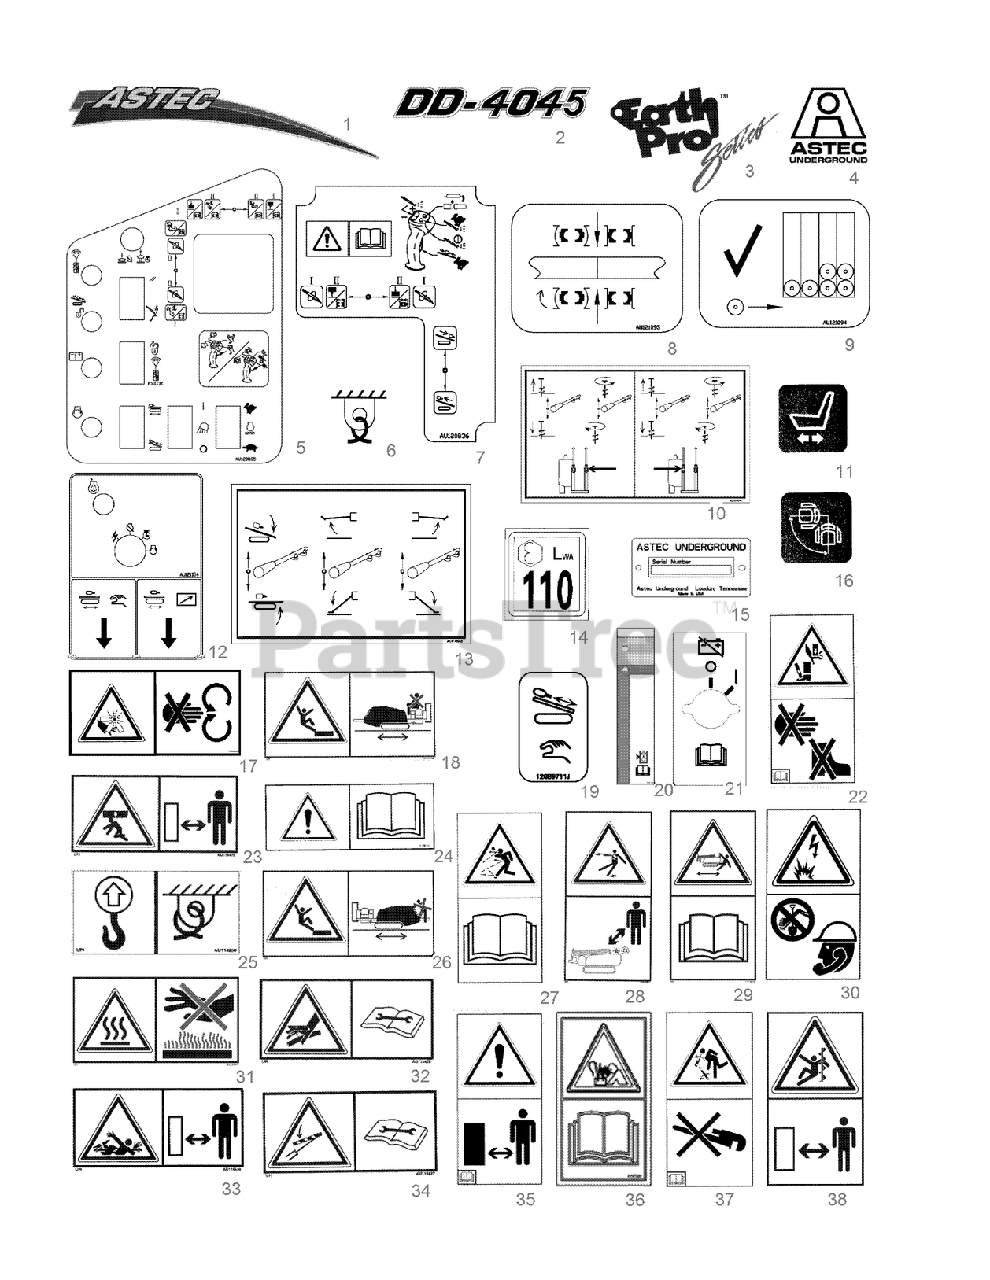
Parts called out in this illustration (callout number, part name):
1	DECAL - Astec, Red and Blue Pattern
2	DECAL - Model DD4045
3	DECAL - Earth Pro, Medium Size
4	DECAL - A, Astec Underground
5	DECAL - Left Joystick Overlay
6	DECAL-Tie Down
7	DECAL - Right Joystick Overlay
8	DECAL - Pipe Breakout Clear
9	DECAL - Pipe Return Clear
10	DECAL - Stakedown Setup
11	DECAL - Seat Fore/Aft
12	DECAL - Rear Controls (Inside Box)
13	DECAL - Stabilizer/Thrust Frame Setup
14	DECAL - Danger, Bystander
15	PLATE - Serial Number
16	DECAL - Seat Pivot In/Out
17	DECAL-Fan Entanglement
18	DECAL - Warning, No Riders (Front), ISO
19	DECAL - Remote Plug
20	DECAL-Hydraulic Oil Level
21	DECAL-Master Disconnect Switch
22	DECAL - Danger, Crush, Hands and Feet, ISO
23	DECAL - Danger, Crush From Above, ISO
24	DECAL - Warning, Read Operators Manual, ISO
25	DECAL-Tie Down / Lift Hook
26	DECAL - Warning, No Riders While Tramming, ISO
27	DECAL - Warning, Flying Objects, ISO
28	DECAL - Danger, Strike Alert Electrocution Hazard, ISO
29	DECAL - Danger, Runover Hazard, ISO
30	DECAL - Call Before You Dig, ISO
31	DECAL-Hot Surface
32	DECAL - Danger, Hydraulic Components Under Pressure, ISO
33	DECAL - Danger, Entanglement Hazard, Small, ISO
34	DECAL - Warning, Use Cylinder Lock For Service, ISO
35	DECAL - Warning, Stand Clear, ISO
36	DECAL-Battery Explosion
37	DECAL - Do Not Use Pipe Wrench, ISO
38	DECAL - Danger, Vertical Auger Entanglement, ISO
